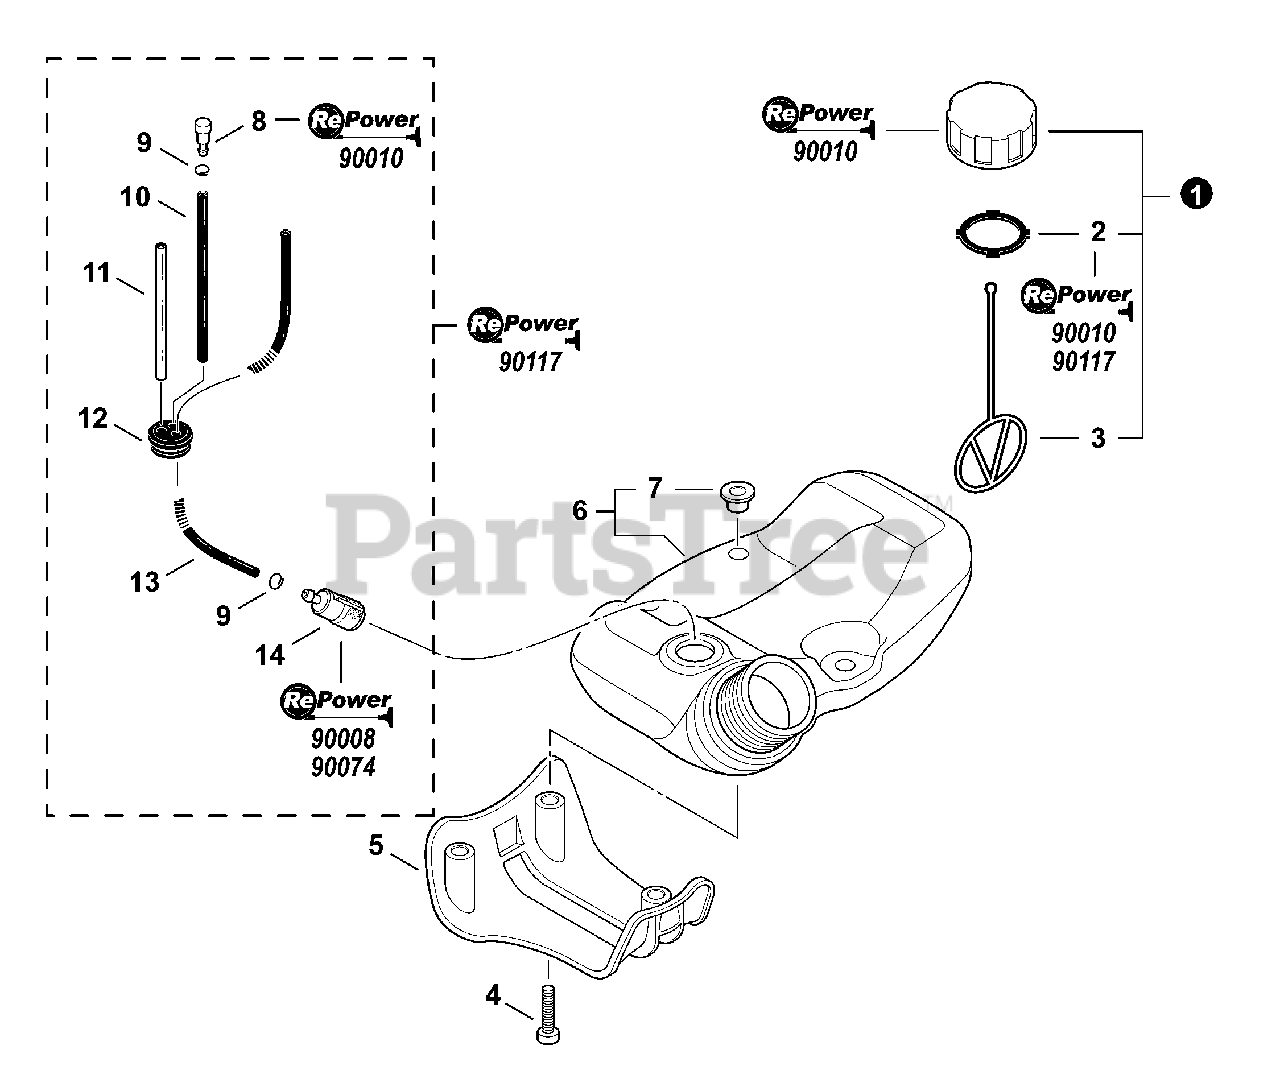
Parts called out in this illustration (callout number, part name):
1	CAP ASSY, FUEL
2	GASKET, FUEL CAP
3	CONNECTOR, CAP L= 123
4	BOLT, TORX 5×25
5	GUARD, FUEL TANK
6	TANK ASSY, FUEL
7	COLLAR 5
8	VENT ASSY
9	CLIP 6 MM
10	PIPE, FUEL 3×5×90 BLACK
11	PIPE, FUEL 3×6×80 CLEAR
12	GROMMET, FUEL
13	PIPE, FUEL 3×5×210 BLACK
14	FILTER, FUEL
